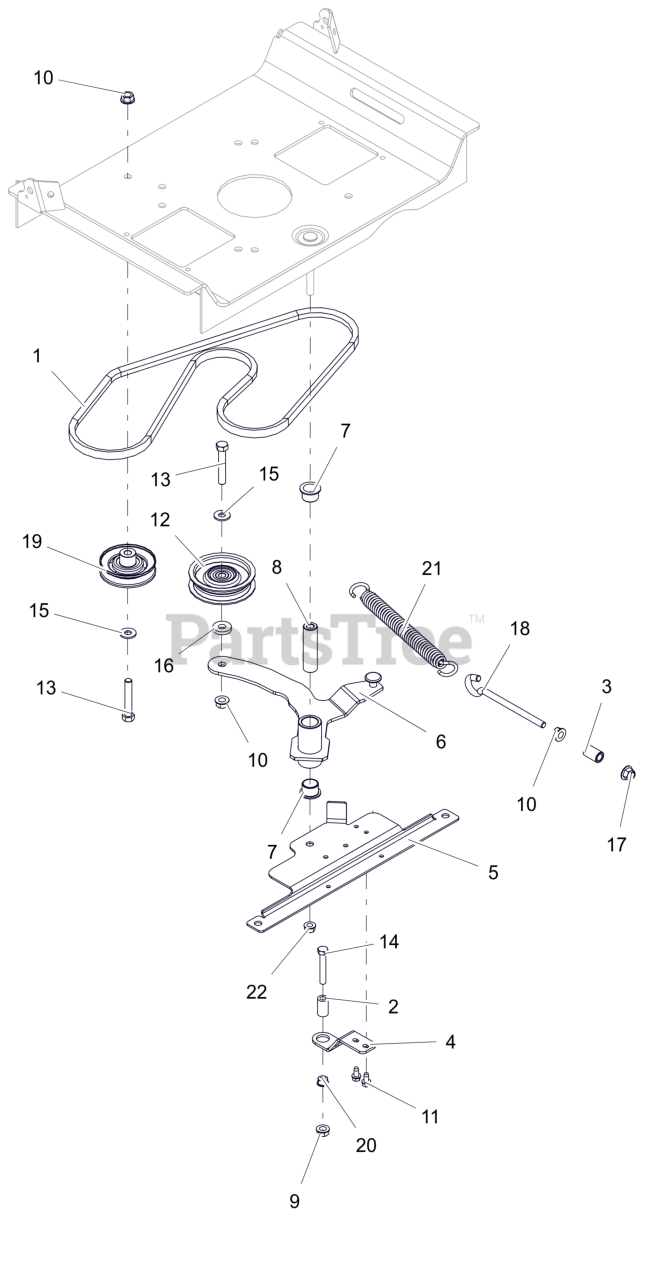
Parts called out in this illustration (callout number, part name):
1	V-BELT, A-RAW EDGE
2	SPACER, RUBBER 5/16 IDX1.0 LG
3	SPACER, .375X.625X.970 (PM)
4	BRKT, CLUTCH STOP (XL)
5	BRKT, IDLER ATTACHMENT (BLACK)
6	WLDMT,GRD DRIVE IDLER ARM-LGR
7	BSHG-FLG 0.75X0.875X.625X1.125
8	BUSHING, SLEEVE .38X.750X2.78
9	NUT, SPNLK-FLG .38-16 G5 ZCC
10	NUT-LK-TOP-FLG .38-16 ZC120
11	SCR-TAP .25-20X.50 HWH ZCC
12	SHEAVE, IDLER -V .38 x 4.00
13	BLT,HEX .38-16X2.25 G5 ZCC
14	BLT, HEX .31-18X2.00 G5 ZCC
15	WSHR,FLT .375X.875X.083 ZCC
16	WSHR, FLT .406X1.00X.188 ZCC
17	NUT,NYL-FLG .38-16 GF ZCC
18	BOLT,.38-16 X 4.25-.62 DIA EYE
19	IDLER, V-3.000 OD
20	NUT,SPNLK-FLG .31-18 G5 ZCC
21	SPRING- EXTENSION
22	NUT-LK-TOP-FLG .312-18 GF ZCC
